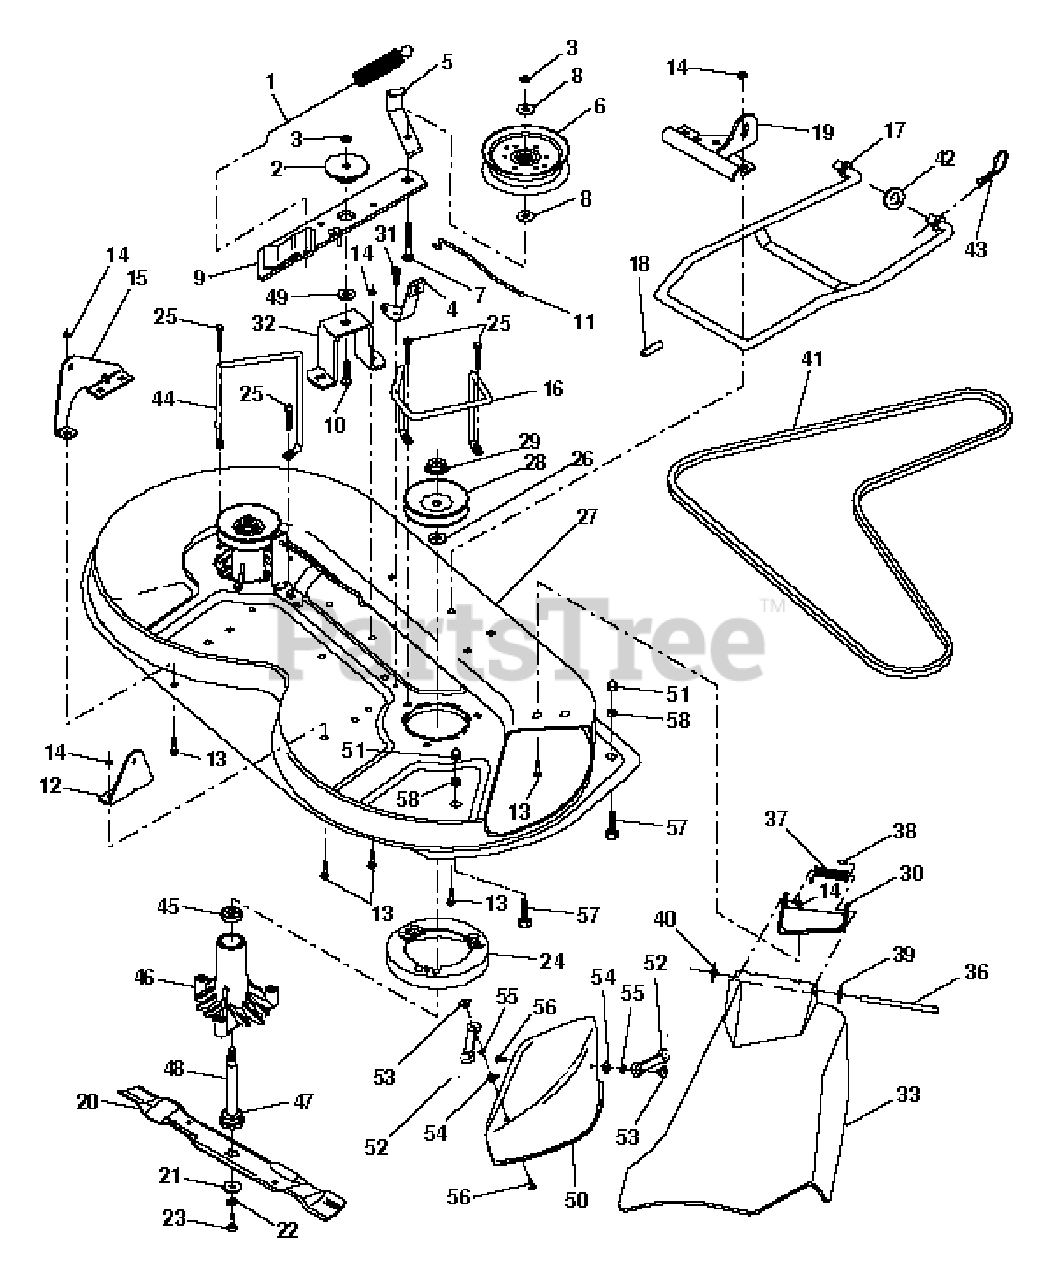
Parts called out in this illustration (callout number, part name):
1	Spring, Mower Clutch
2	Spacer, Retainer
3	Nut, Crownlock 3/8-16
4	Brake Asm.
5	Guide, Belt Idler
6	Pulley, Flat Idler
7	Bolt, Carr. 3/8-16 x 1-3/4 Gr. 5
8	Washer 13/21 x 7/8 x 10 Ga.
9	Arm Asm., Idler Mower
10	Bolt, Carriage 3/8-16 x 1-1/4
11	Rod, Brake
12	Bracket, Lift R. H. Rear
13	Bolt, Carriage 5/16-18 x 3/4
14	Nut, Crownlock 5/16-18
15	Bracket, Lift L. H. Rear
16	Keeper, R. H.
17	Link, Asm. Mower Stabilizer
18	Pin, Drive
19	Bracket, Asm. Front
20	Blade Mulching
21	Washer, Hard
22	Washer, Lock 3/8
23	Bolt 3/8-24 x 1-1/4 Gr. 8
24	Stripper
25	Screw Thdrol Hex Hd
26	Washer.150 Thk.
27	Deck Assembly
28	Pulley, Mandrel
29	Nut, Flangelock 9/16
30	Bracket, Asm. Deflector
31	Screw, Hex Wsh. Thdrol. 5/16-18 x 1/2
32	Arm, Support Idler Mower
33	Deflector
36	Rod, Hinge
37	Spring, Torsion Deflector
38	Cap, Sleeve
39	Washer 11/32 x 5/8 x 16 Ga.
42	Washer 11/32 x 5/8 16 Ga.
43	Retainer, Spring
44	Keeper, L. H.
46	Housing Mandrel Vented
48	Shaft, Mandrel
49	Washer, Hardened
50	Mulcher Plate
51	Acorn Nut 5/16-18
52	Latch Hook
53	Nut, Weld
54	Washer #10
55	Washer, Lock #10
56	Screw
57	Bolt, Hex 5/16-18 x 1
58	Locknut 5/16-18
58	Mandrel Asm.
58	Deck, Mower Complete
